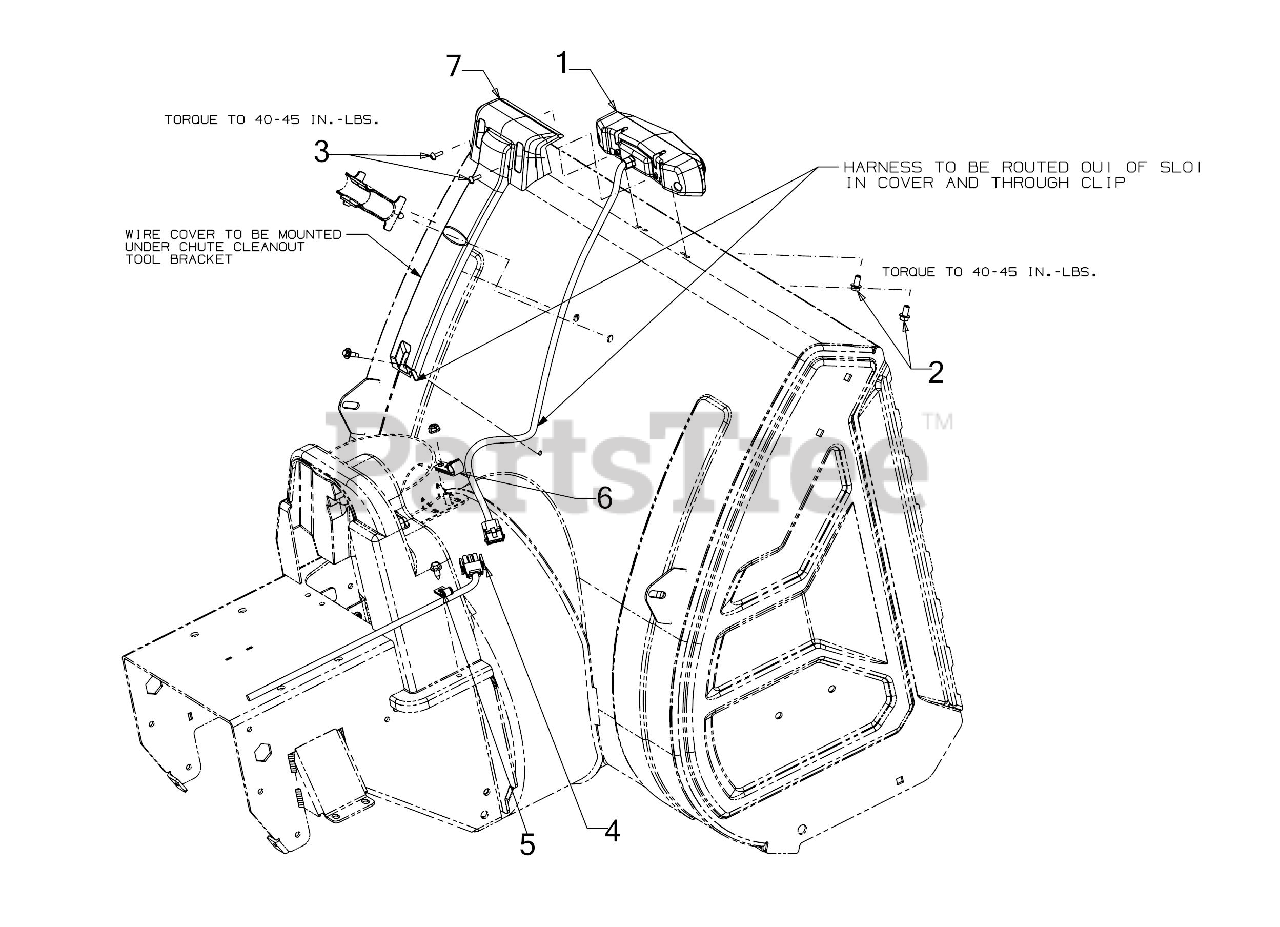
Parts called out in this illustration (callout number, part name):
1	LED LIGHT BAR HEADLIGHT ASSEMBLY
2	HEX SCREW 1/4-15 x .50
3	SCREW 8/16 x .500
4	LED HEADLIGHT HARNESS
5	MOUNTING CLAMP
6	HEADLIGHT HARNESS CLAMP
7	LED LIGHT BAR COVER
